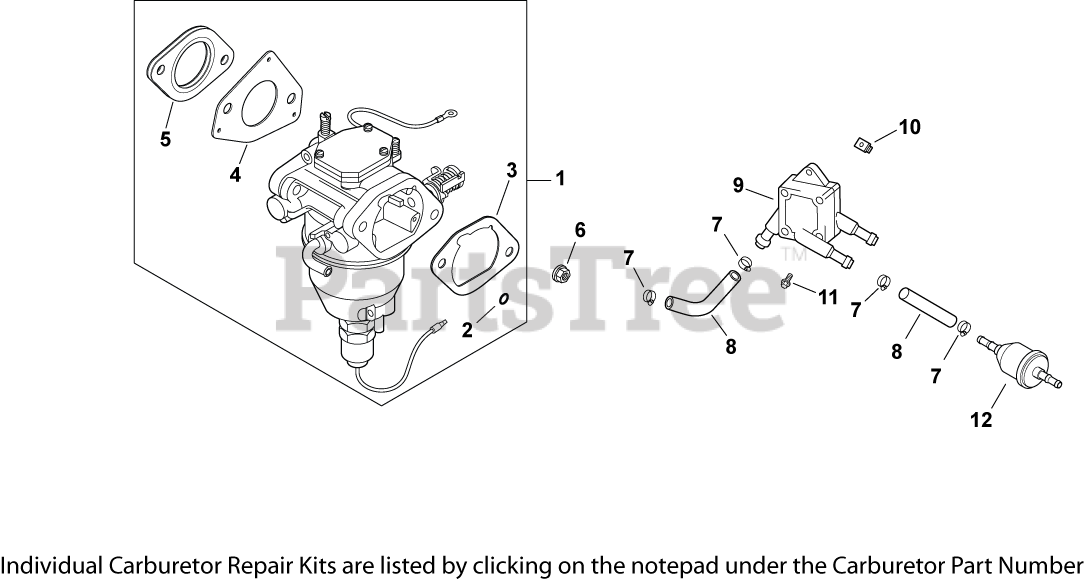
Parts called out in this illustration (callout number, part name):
1	KIT, CARBURETOR w/GASKETS
3	GASKET, AIR CLEANER BASE
4	GASKET, CARBURETOR
5	GASKET, CARBURETOR
6	NUT, FLG M6X1.0
7	CLAMP, HOSE (KM)-USE 25 237 31-S
8	HOSE,LW PERM.FUEL 24.00"-USE 25 111 81-S
9	PUMP, FUEL
10	NUT, PLASTIC - BLACK
11	SCREW, TAP M6X1.7X18
12	FILTER, FUEL
